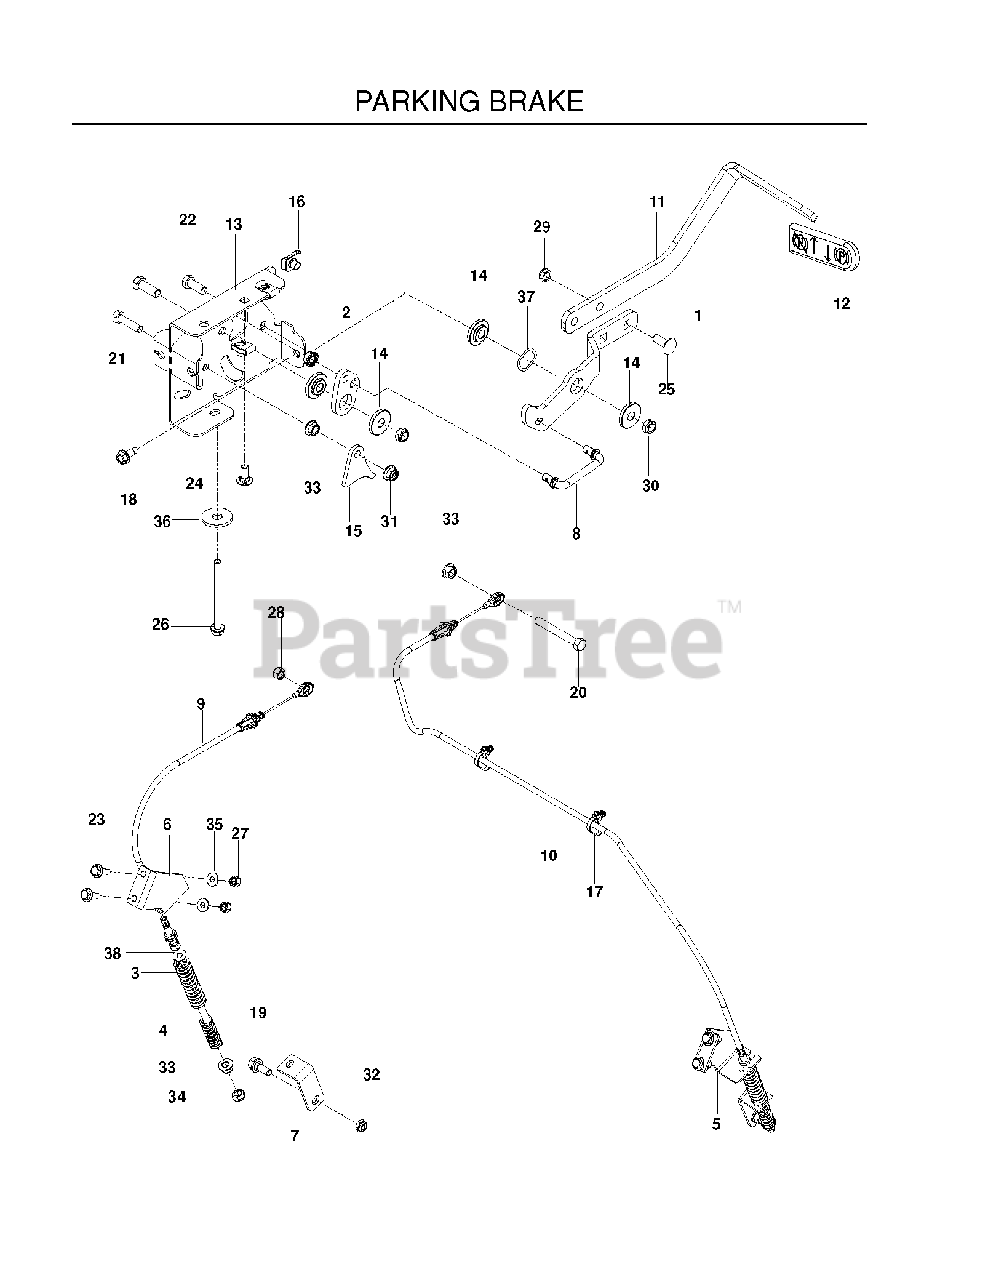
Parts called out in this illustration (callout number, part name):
1	LEVER, BRAKE
2	BELLCRANK, BRAKE
3	SPRING, RETURN
4	SPRING, ENGAGEMENT
5	BRKT, BRAKE RT, BLK
6	BRKT, BRAKE LT, BLK
7	BRKT, BRAKE, BLK
8	LINKAGE, BRAKE
9	RP_CABLE, BRAKE, SHORT
10	RP_CABLE, BRAKE, LONG
11	ARM, BRAKE
12	GRIP, PARK BRAKE
13	MOUNT, BRAKE WLDMT
14	BUSHING, BRAKE
15	ACTUATOR, SWITCH
16	U-CLIP 5/16-18 NUT RETAINER
17	TIE WRAP, 8-3/8", W/CLIP
18	BOLT 5/16-18 X 3/4
19	BOLT, SHOULDER
20	HCS 5/16-18 X 2 1/2 TPBLT
21	HCS 5/16C X 1
22	HCS 3/8-16X1.GRD.5.ZD
23	HCS 1/4-20X7/8 GR5
24	BOLT 5/16C X 3/4" CARRIAGE
25	RHSNB 3/8C X 1
26	HHFS 5/16-18 X 3 3/4
27	RP_NUT 1/4-20 NYLOC
28	NUT 5/16 NYLOC
29	NUT 3/8-16 HEX FLG NYLOC ZD
30	NUT HEX 3/8-16 NYLON, THIN
31	5/16-18 NYLOC FLANGE NUT
32	5/16-18 THIN PROF NY
33	NUT 5/16C WHIZ
34	NUT 5/16-18 HEX JAM ZD
35	WASHER 1/4 SAE
36	WASH USS FLAT 1/2
37	WASHER, .825 X 1.087, WAVE
38	WASHER 3/8 SAE FLAT
